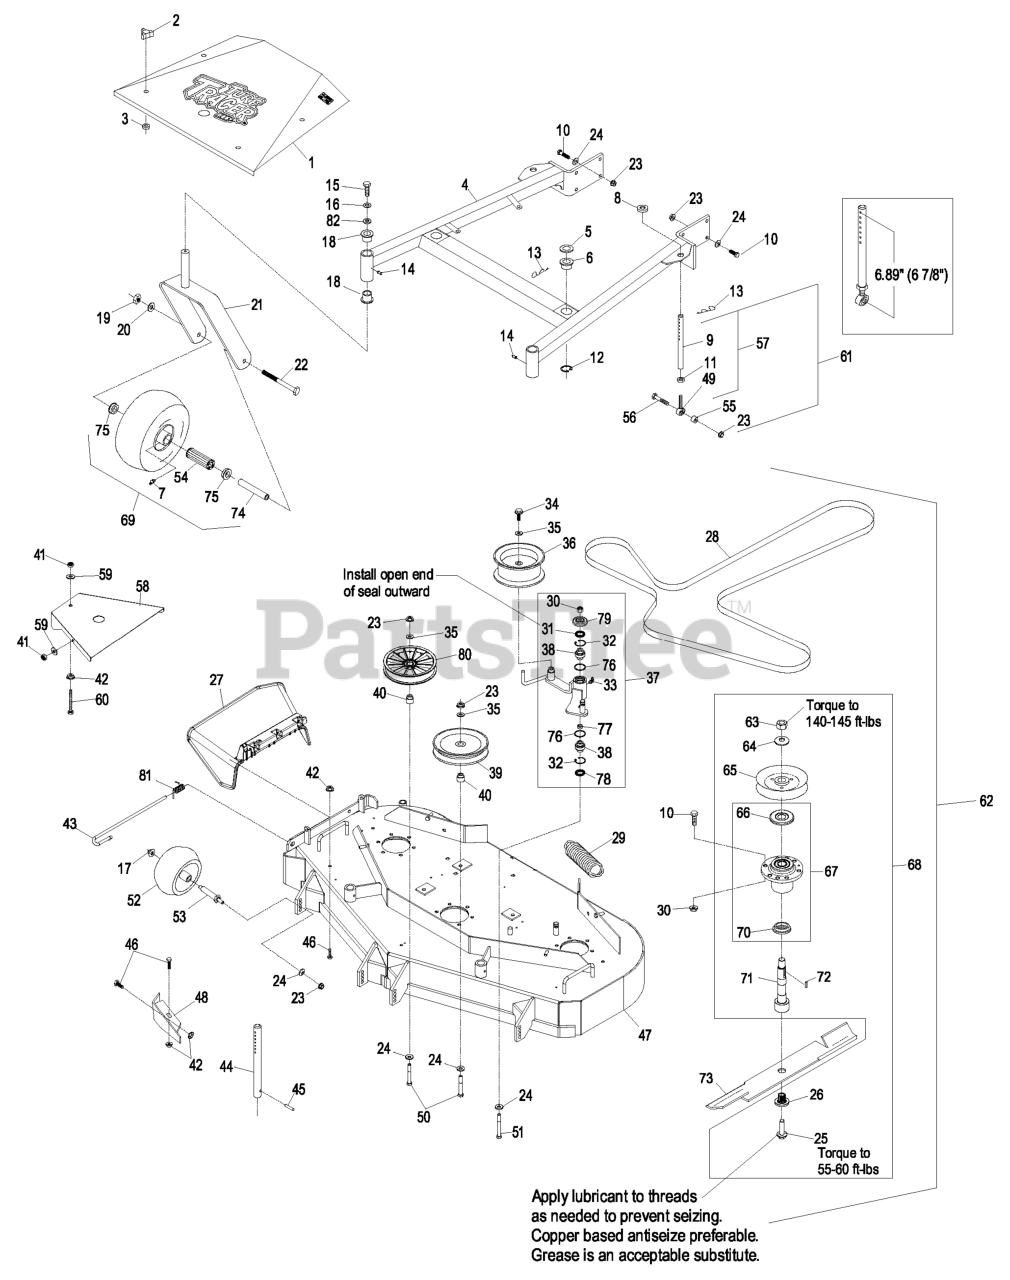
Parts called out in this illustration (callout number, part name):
1	ASM,SHIELD W/DECALS 48 TT
2	KNOB-3 PRONG
4	DECK SUPPORT W/BSHGS 48"
5	SPACER-DECK SUPPORT
6	BUSHING-DECK
7	FITTING-GREASE
9	LINK,SUPPORT
10	SCREW-HH
11	NUT-HJ
12	RING-RETAINING
13	PIN,HAIR COTTER
14	FITTING-GREASE
15	SCREW-HH
16	WASHER-LOCK
17	Nut-Nyloc 3/8-16 Flg
18	BEARING-FLANGED
19	NUT-HH
20	WASHER-LOCK
22	SCREW-HH
23	NUT-HHF, WHIZ
24	WASHER-BELLEVILLE
25	SCREW,SEMS 1/2-20 X 2.19
26	BUSHING,SPLINED
27	CHUTE DEFLECTOR XRK M056
28	BELT - V, B
30	NUT-LOCK, NI
31	SEAL-LIP, SINGLE
32	RING-SNAP
33	FITTING-GREASE, 90 DEG
34	SCREW-HHF
35	WASHER-FLAT
37	KIT, DECK IDLER TTHP48&52
38	BEARING-SPHERICAL
39	PULLEY-IDLER
40	BUSHING-IDLER
41	NUT-LOCK, NI
43	PIN-CHUTE
44	ROD,DECK SUPPORT
46	SCREW-HH
47	ASM,DECK W/DECALS TTHP/MH
49	BALLJOINT
50	SCREW-HH
51	SCREW-HH
52	ROLLER-SCALP, ANTI
54	BEARING
56	SCREW-HH
58	SHIELD,BELT
59	WASHER-FLAT
60	BOLT,TAP HH
61	KIT,SUPPORT LINK W/PIN
62	Asm, Deck Complete
65	SHEAVE,W/HUB 5.72
66	GUARD-BEARING, TOP
67	KIT, CUTTER HOUSING
68	ASM, CUTTER HSG
69	KIT, SP CASTER WHEEL REPL
70	SPACER-GUARD, BOTTOM
71	KIT, SPLINED SPINDLE 103-
72	KEY-RECTANGLE
75	BUSHING
78	SEAL-LIP, DOUBLE
79	GUARD-TOP
80	PULLEY,IDLER 5"
81	SPRING, TORSION
